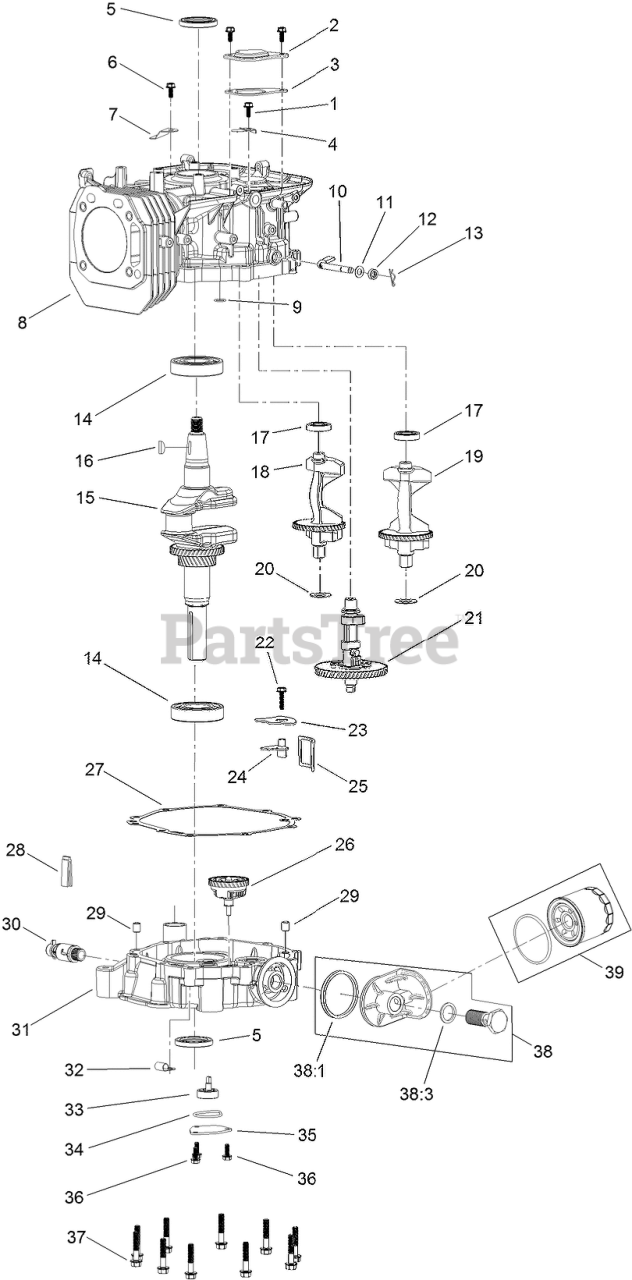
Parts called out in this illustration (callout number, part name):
1	SCREW-HHF
2	PLATE-BREATHER
3	GASKET-BREATHER
4	VALVE-REED
5	SEAL-OIL
6	SCREW-HHF
7	RETAINER
8	CRANKCASE
9	O-RING
10	SHAFT-GOVERNOR
11	WASHER-PLAIN
12	SEAL-OIL
13	PIN-HAIR
14	BEARING-BALL
15	CRANKSHAFT
16	KEY-WOODRUFF
17	BEARING-BALL
18	BALANCER-RH
19	BALANCER-LH
20	WASHER
21	CAMSHAFT
22	SCREW-HHF
23	COVER-STRAINER, OIL
24	PLATE-BAFFLE, OIL
25	STRAINER-OIL
26	GEAR-GOVERNOR
27	GASKET-CRANKCASE
28	DEFLECTOR-OIL, RUBBER
29	PIN-DOWEL
30	VALVE-DRAIN, OIL
31	COVER-CRANKCASE
32	CLAMP-J
33	OIL PUMP ASM
34	SEAL-PUMP, OIL
35	COVER-PUMP, OIL
36	SCREW-HHF
37	SCREW-HHF
38	OIL ADAPTOR KIT
38:1	SEAL-ADAPTOR, OIL
38:3	WASHER-FILTER, OIL
39	FILTER-OIL
